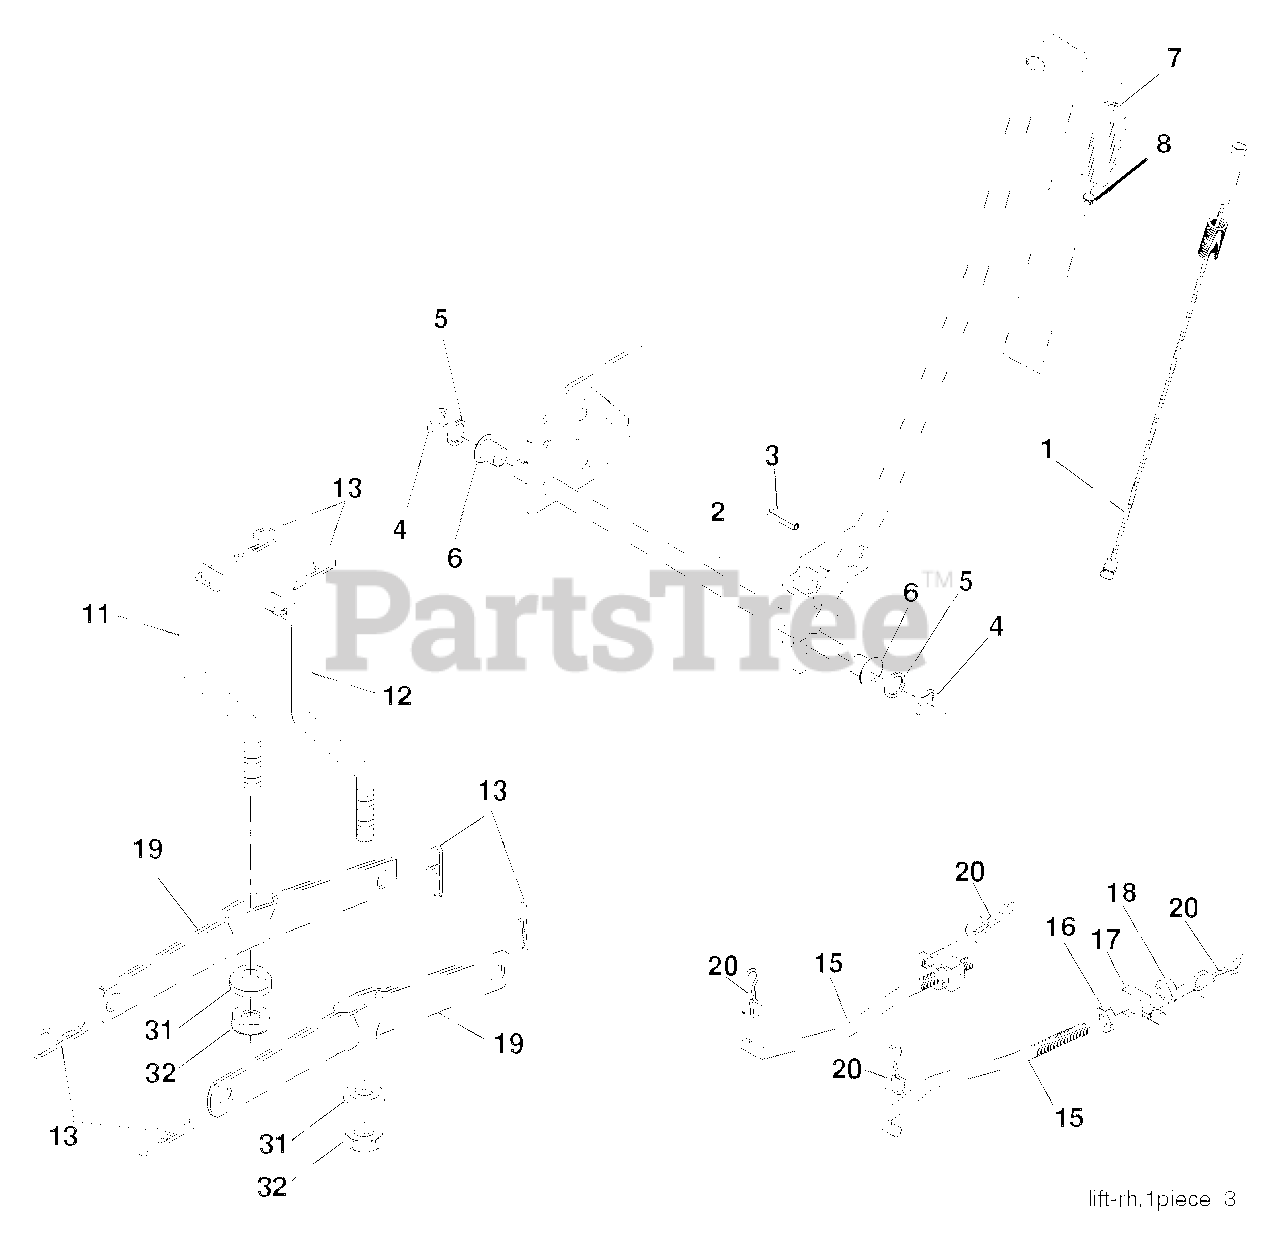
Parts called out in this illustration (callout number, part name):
1	PLUNGER.ASM.LIFT.LVR.BLK.17.32
2	SHAFT ASM R HANDLE
3	PIN GROOVE.
4	RETAINING RING LT
6	BEARING.NYLON
7	GRIP
8	PLUNGER BUT KIT
11	LINK LIFT LH
12	Lift Link Assembly, RH
13	RETAINER-SPRNG RB
15	LINK.SUSPENSION.FRONT
16	NUT.HEX.JAM.1/2-13
17	TRUNNION
18	NUT.LK.W/WSH.1/2.
19	ARM.REAR.SUSPENSION
20	PIN.COTTER.7/16.BOW TI.
31	BEARING.PIVOT.LIFT
32	NUT CROWNLOCK 3/8-24
